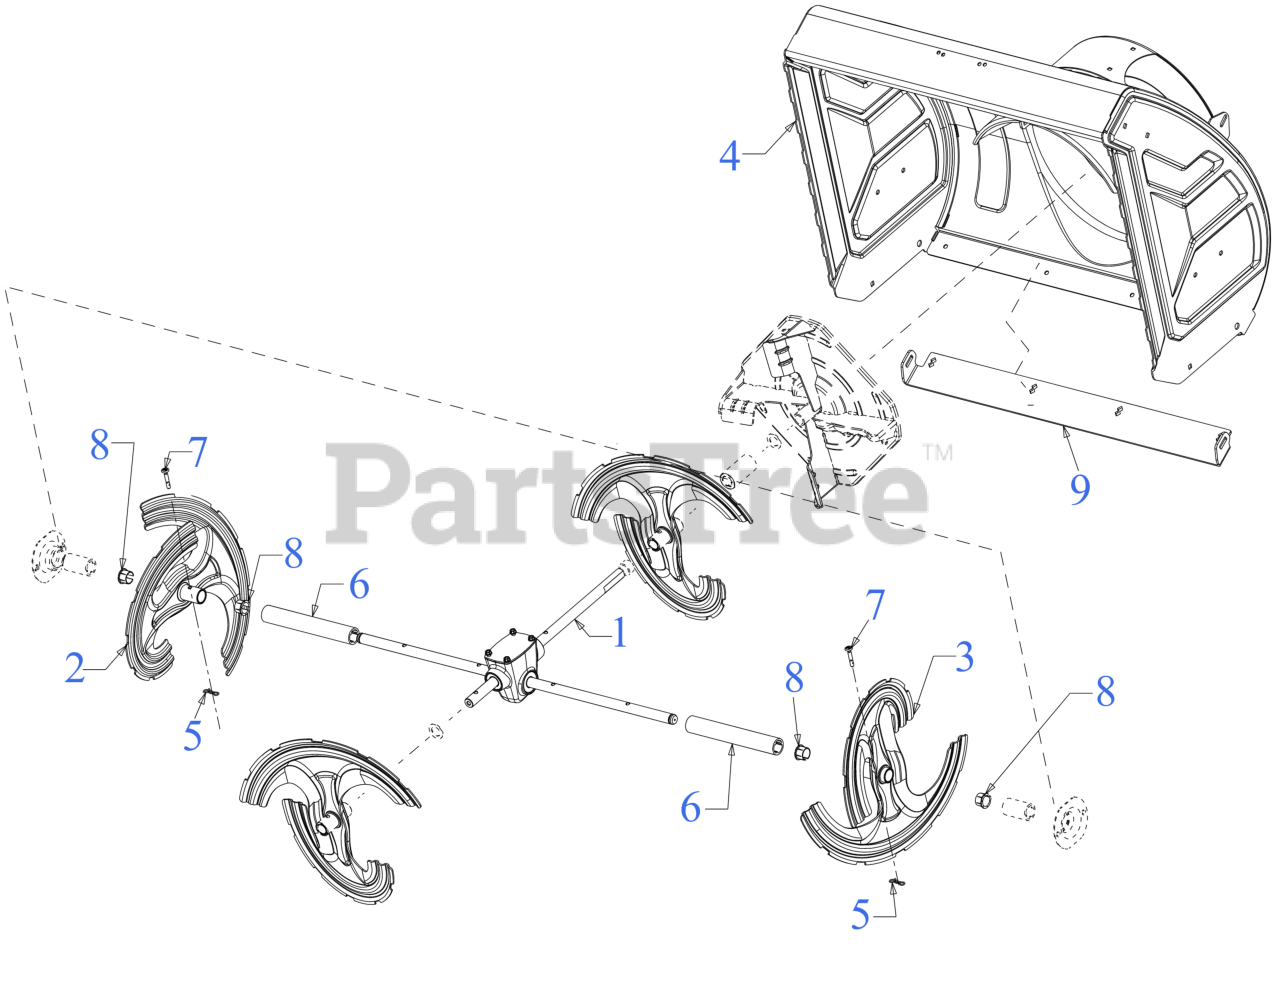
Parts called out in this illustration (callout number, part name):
1	30" AUGER GEARBOX ASSEMBLY
5	BOW TIE COTTER PIN 1/4-5/16
6	SPACER 1.25OD x .75ID x 8.15LG
7	SHEAR PIN (.25 x 1.50)
7	Cub Cadet SHEAR PINS (3X SNOW)
7	Troy-Bilt SHEAR PINS (3X SNOW)
7	KIT-SHEAR PIN 3 STAGE (05273/06654)
8	FLANGE BUSHING
